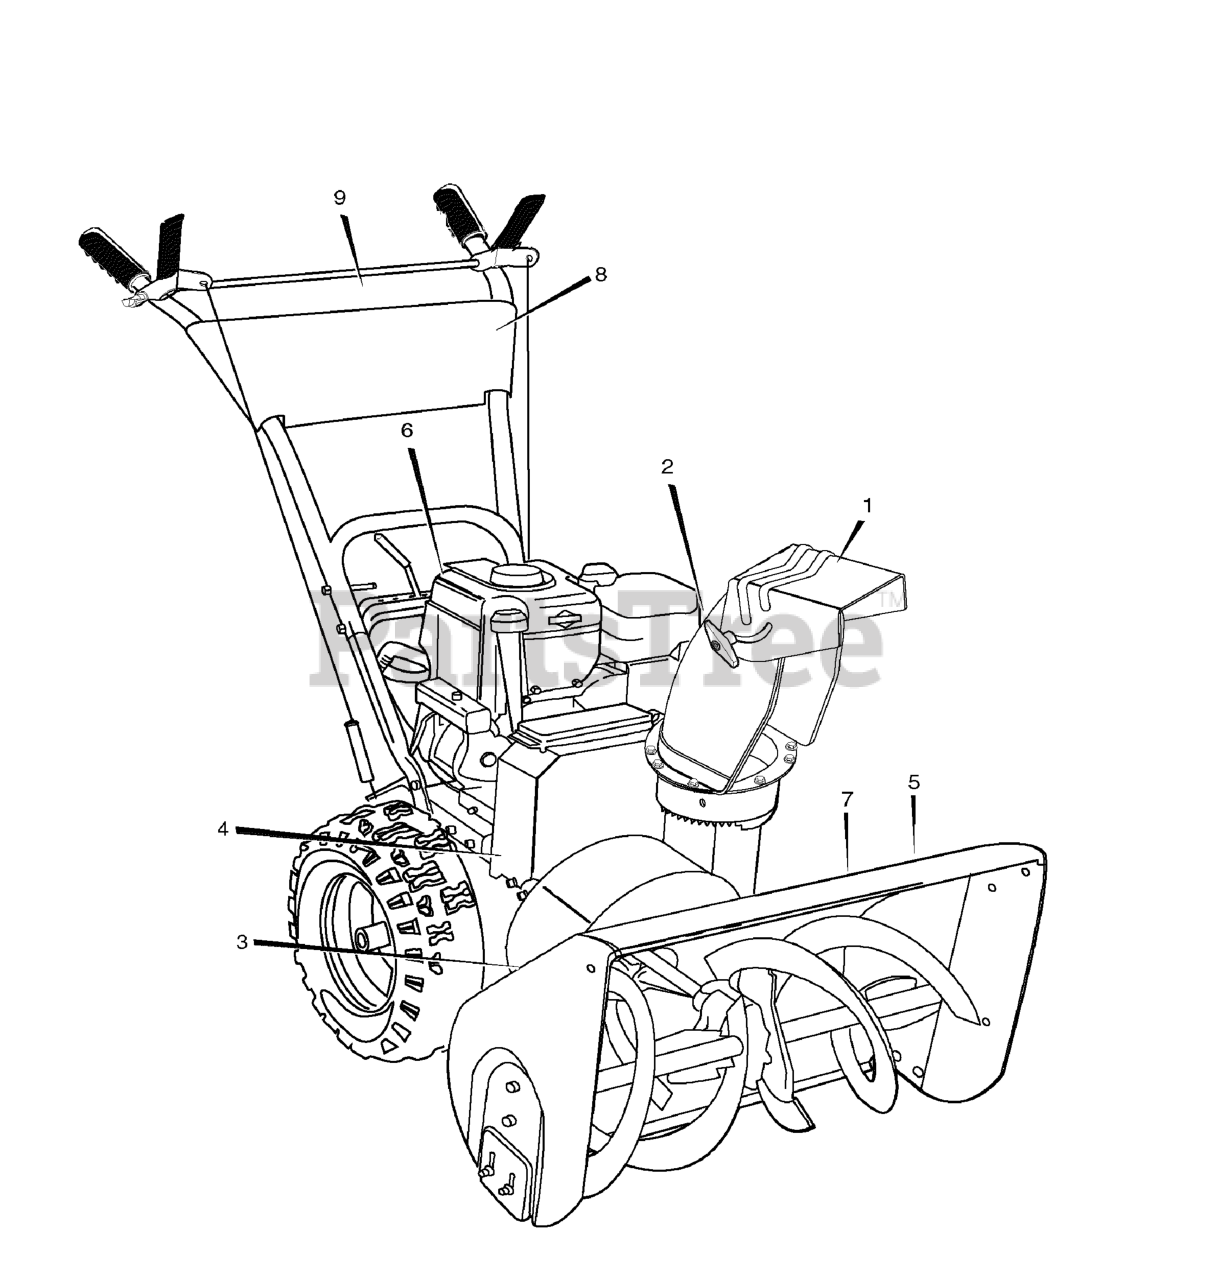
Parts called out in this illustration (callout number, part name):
1	DECAL, THROWN OBJECTS
2	DECAL, DANGER CHUTE
3	DECAL, ISO AUGER FR/EN
4	DECAL, BELT STRETCH
5	DECAL, CLEAN CLEAR BRUSH
6	DECAL, SPEED CONTROL
7	DECAL, MURRAY DASH
8	DECAL, MURRAY PANEL
9	DECAL, AUGER CONTROL SYMBOLS
